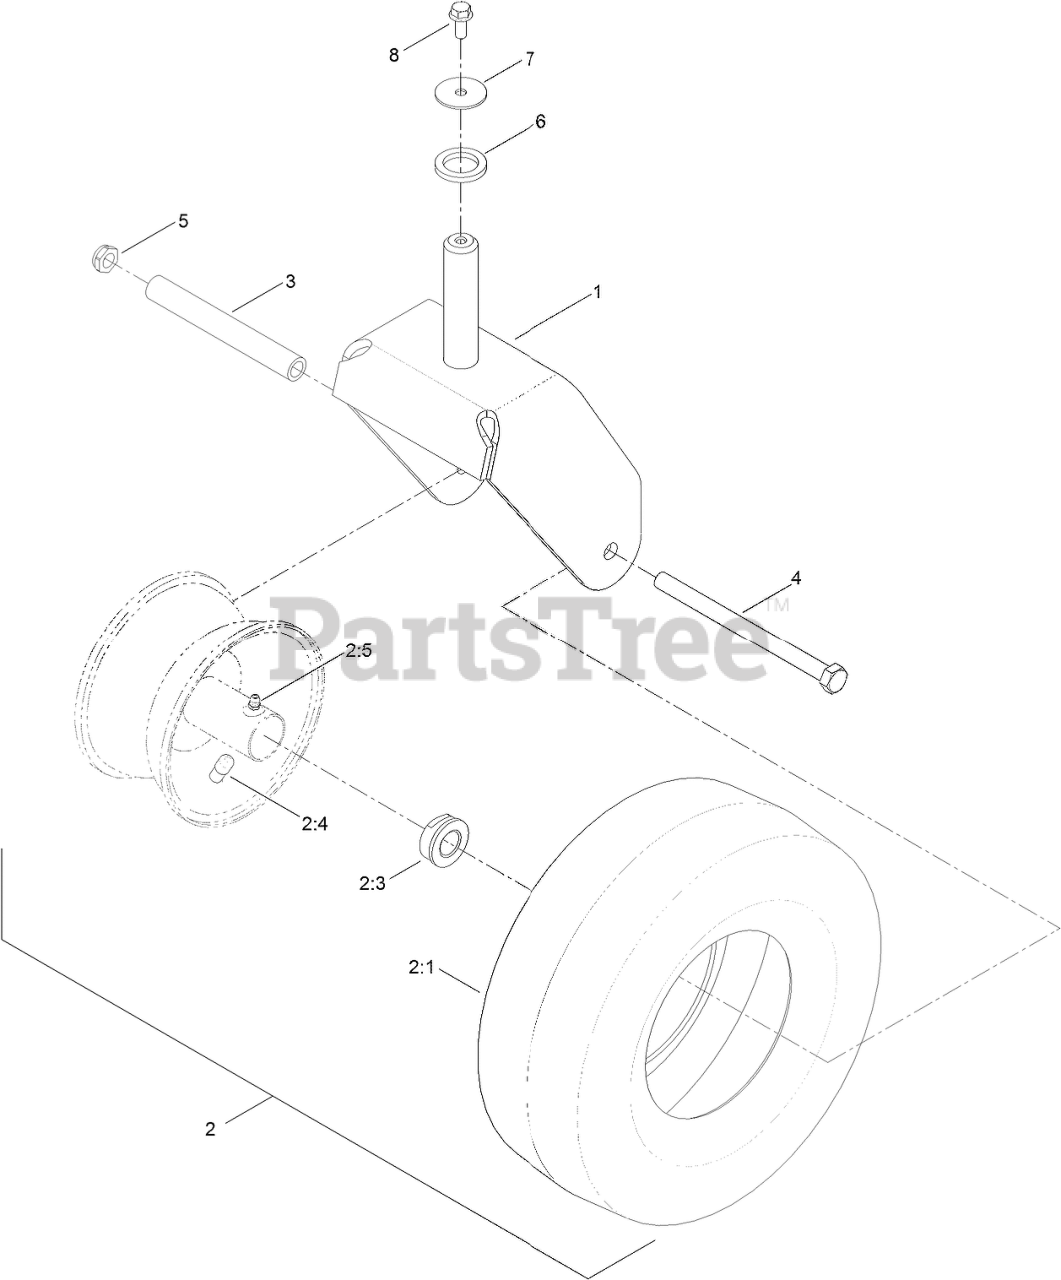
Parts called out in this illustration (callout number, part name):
1	FORK-CASTER
2	13 INCH WHEEL AND TIRE ASM
2:1	TIRE-13 Inch
2:3	BUSHING-FLANGE
2:4	STEM-VALVE
2:5	FITTING-GREASE
3	SPANNER
4	SCREW-HH
5	NUT-HEX
6	WASHER-THRUST
7	WASHER-FLAT
8	SCREW-HHF
